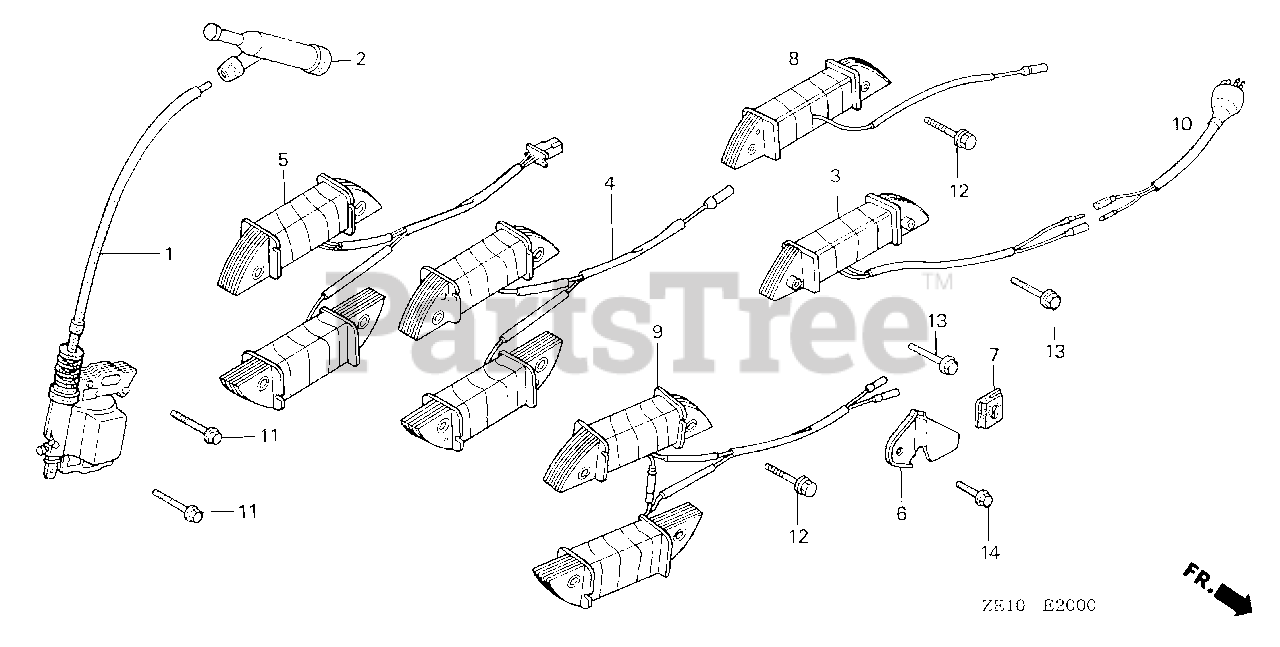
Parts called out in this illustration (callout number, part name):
1	COIL ASSY., IGNITION
2	CAP ASSY., NOISE SUPPRESSOR (NICHIWA Y-EZ RTFM256)
11	BOLT, FLANGE (6X28) (CT200)
11	BOLT, FLANGE (6X25) (CT200)
